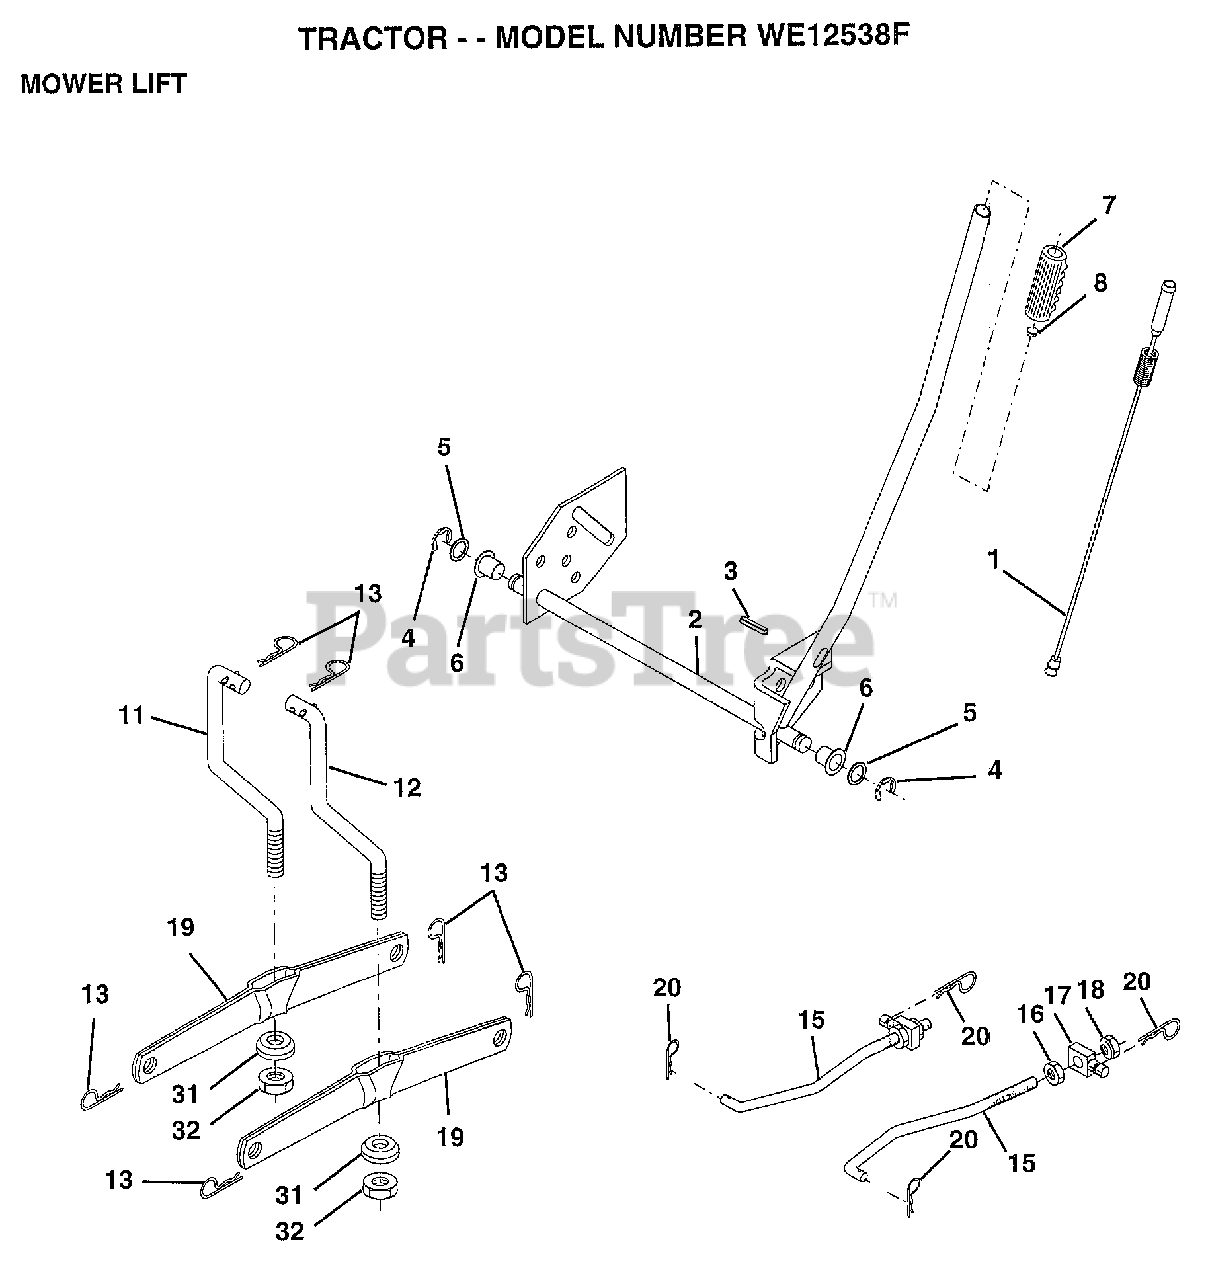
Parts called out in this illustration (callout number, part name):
1	WIRE ASM W.SPRING
2	"SHAFT ASM LIFT,RH"
3	PIN-GROOVE LT
5	WASHER
6	NYLON BEARING
7	GRIP
15	LINK.FRONT
16	NUT
17	TRUNION
18	NUT LTV
19	ARM SUSP REAR
20	RETAINER SPRING
31	BEARING PVT LH
32	NUT.CROWNLOCK.3/8
